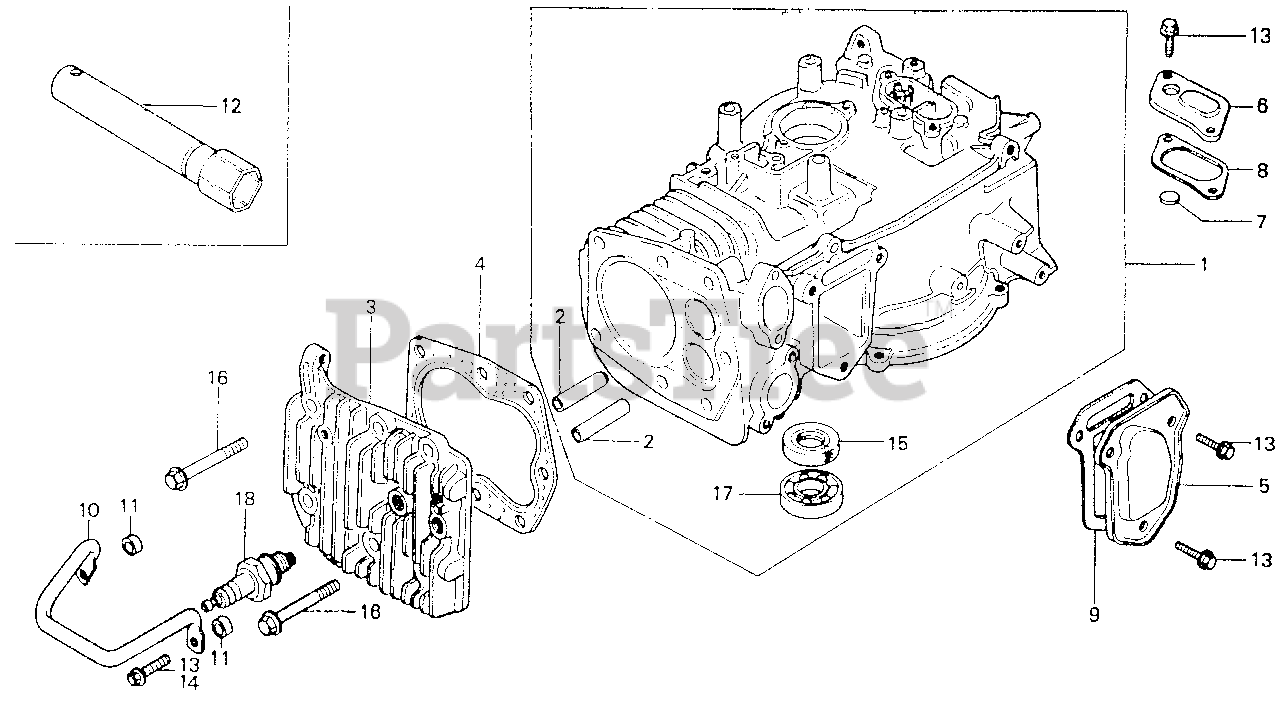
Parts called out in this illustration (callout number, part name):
1	CYLINDER ASSY.
2	GUIDE, VALVE (OVER SIZE)
3	CYLINDER HEAD
4	GASKET, CYLINDER HEAD
5	COVER, TAPPET
6	CAP, BREATHER CHAMBER
7	VALVE, BREATHER
8	GASKET, BREATHER CAP
9	GASKET, TAPPET COVER
10	GUARD, PLUG
11	COLLAR, ROTO-STOP
12	WRENCH, SPARK PLUG (NOT AVAILABLE)
13	BOLT, FLANGE (6X12) (CT200)
14	BOLT, FLANGE (6X20) (CT200)
15	OIL SEAL (25X41X6)
16	BOLT, FLANGE (8X45)
17	BEARING, RADIAL BALL (6205)
18	SPARK PLUG (BMR6A) (NGK)
18	SPARK PLUG (W20MR-U) (DENSO) (NA USE ALT:98073-56744)
